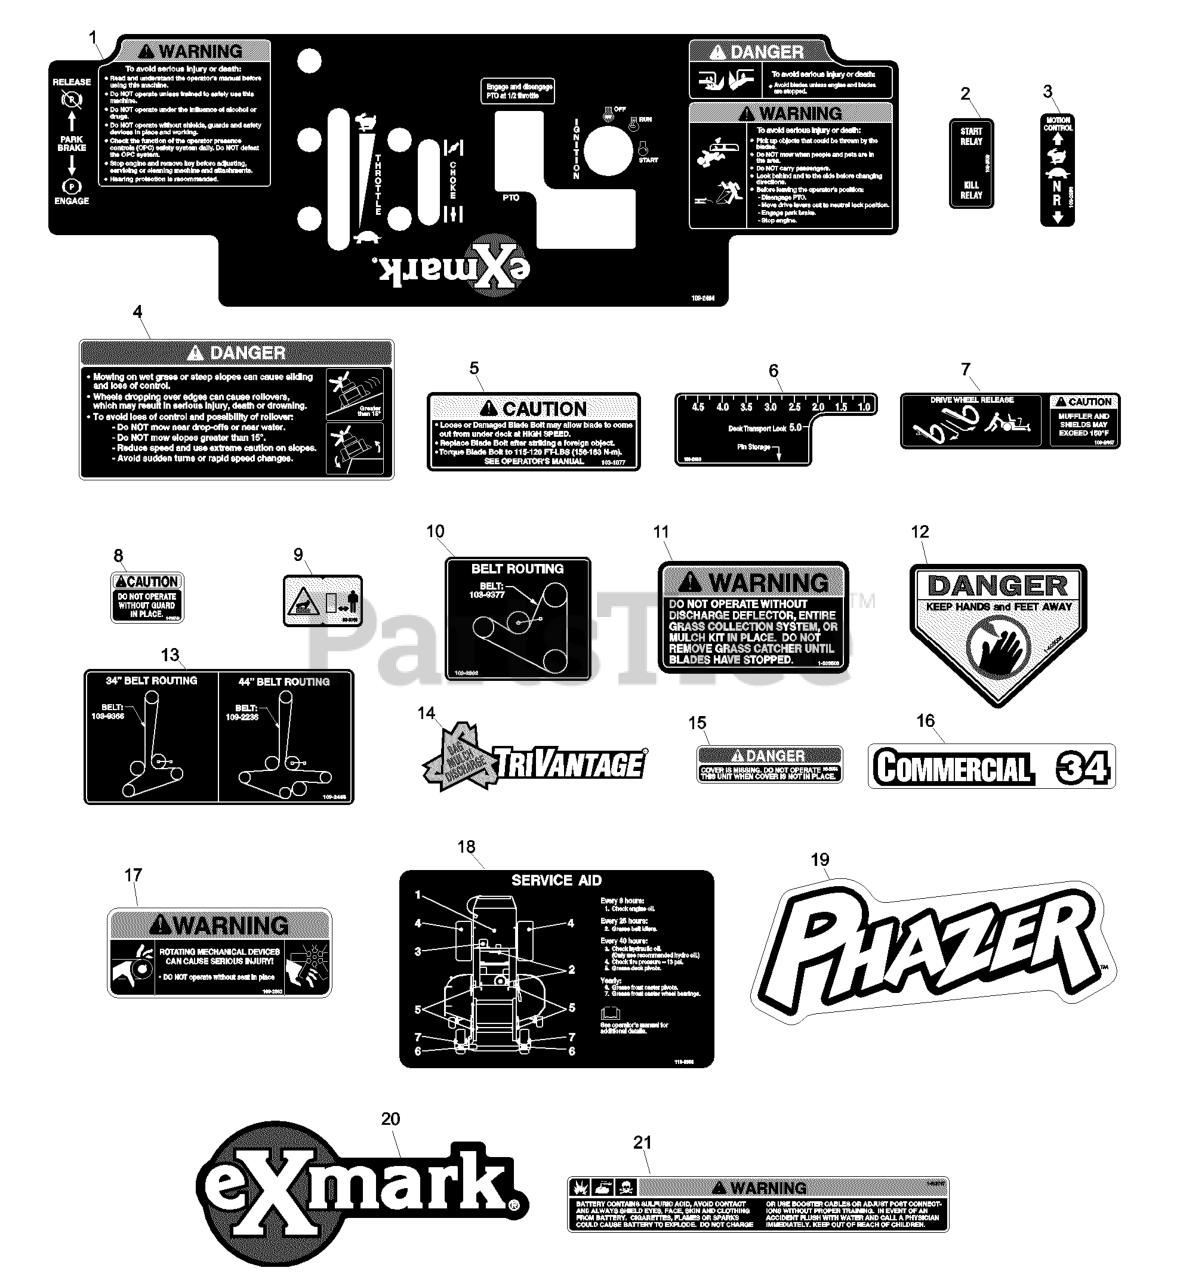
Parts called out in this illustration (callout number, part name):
1	DECAL,CONSOLE
2	DECAL-RELAY
3	DECAL-CONTROL, MOTION
4	DECAL-SLOPE, DANGER
5	DECAL,BOLT TORQUE
6	DECAL-HEIGHT, DECK
7	DECAL,ZT DUMP
8	DECAL-GUARD
9	DECAL-SURFACE, HOT
10	DECAL,BELT ROUTING
11	DECAL-WARNING, DISCHARGE
12	DECAL-DANGER
13	DECAL,BELT ROUTING 34/44
15	DECAL-COVER, MISSING
16	DECAL,COMMERICAL 34
17	DECAL-DEVICES, ROTATING
18	DECAL,SERVICE AID PHAZER
19	DECAL,PHAZER
20	DECAL,EXMARK LOGO
21	DECAL-BATTERY
